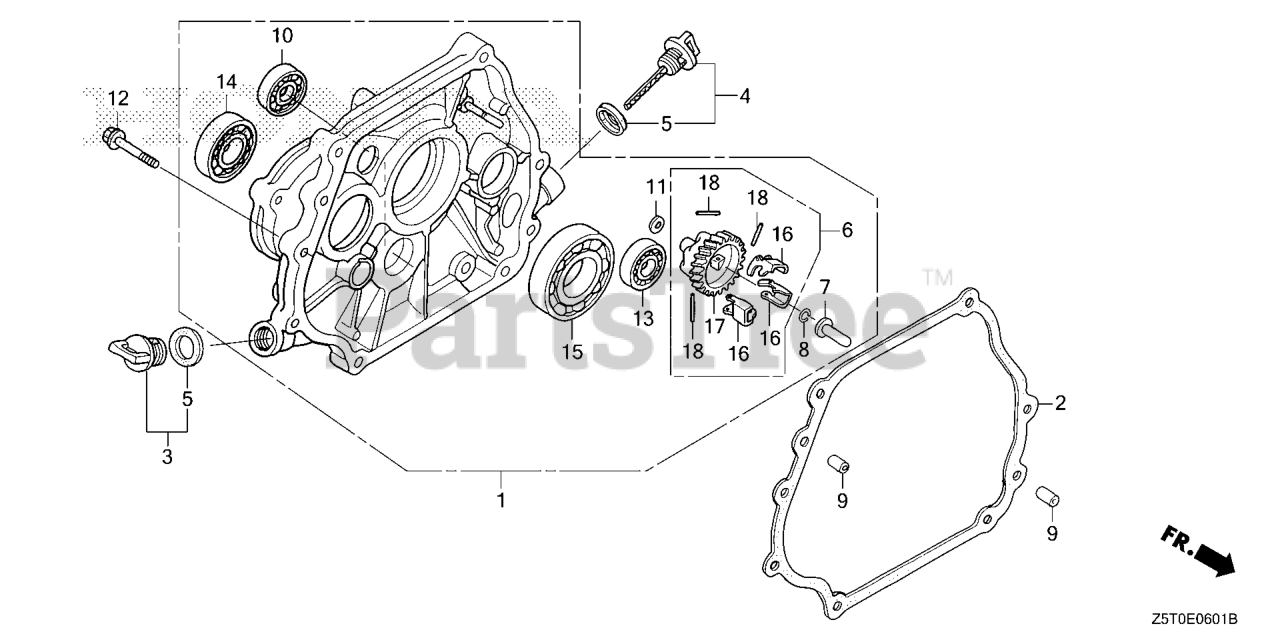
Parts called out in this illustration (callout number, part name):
1	COVER ASSY., CRANKCASE
2	GASKET, CRANKCASE COVER
3	CAP ASSY., OIL FILLER
4	CAP ASSY., OIL FILLER
5	GASKET, OIL FILLER CAP
6	GOVERNOR ASSY.
7	SLIDER, GOVERNOR
8	CLIP, GOVERNOR HOLDER
9	PIN, DOWEL (8X12)
10	BEARING, RADIAL BALL (6202)
11	WASHER, PLAIN (6MM)
12	BOLT, FLANGE (8X40) Use up to Engine SN 1003236.
13	BEARING, RADIAL BALL (6202) (FUJIKOSHI)
13	BEARING, RADIAL BALL (6202)
14	BEARING, RADIAL BALL (6204)
15	BEARING, RADIAL BALL (6207)
16	WEIGHT, GOVERNOR
17	HOLDER, GOVERNOR WEIGHT
18	PIN, GOVERNOR WEIGHT
